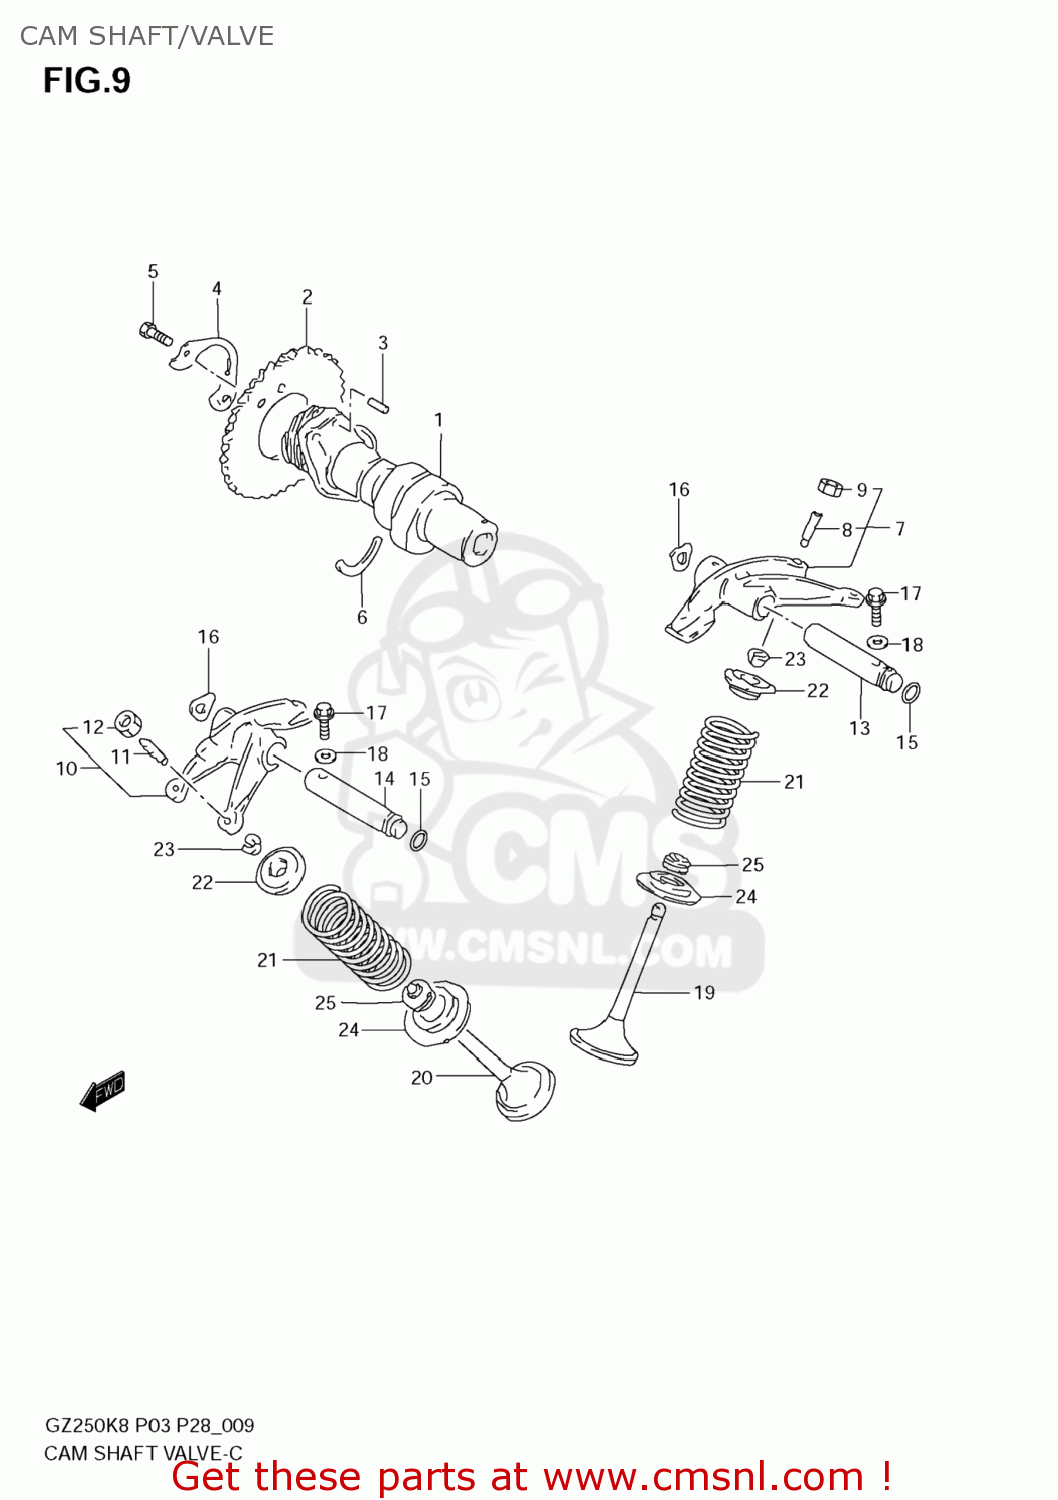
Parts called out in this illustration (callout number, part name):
1	CAMSHAFT
2	SPROCKET,CAMSHAFT(NT:42)
3	PIN
4	WASHER,SPROCKET
5	BOLT(6X12.5)
6	C RING
7	ARM,VALVE ROCKER INTAKE
8	SCREW,TAPPET ADJUSTING
9	NUT,TAPPET ADJUSTING
10	ARM,VALVE ROCKER EXHAUST
11	SCREW,TAPPET ADJUSTING
12	NUT,TAPPET ADJUSTING
13	SHAFT,VLV ROCKER ARM IN(L:91.5
14	SHAFT,VLV ROCKER ARM EXH(L:76)
15	O RING(D:1.9,ID:8.6)
16	WASHER
17	SCREW
18	GASKET(5.8X13X1.2) (NAS)
19	VALVE,INTAKE
20	VALVE,EXHAUST
21	SPRING,VALVE
22	RETAINER,VALVE SPRING
23	COTTER VALVE
24	SEAT,VALVE SPRING
25	SEAL,OIL(5.5X11X8.2)
